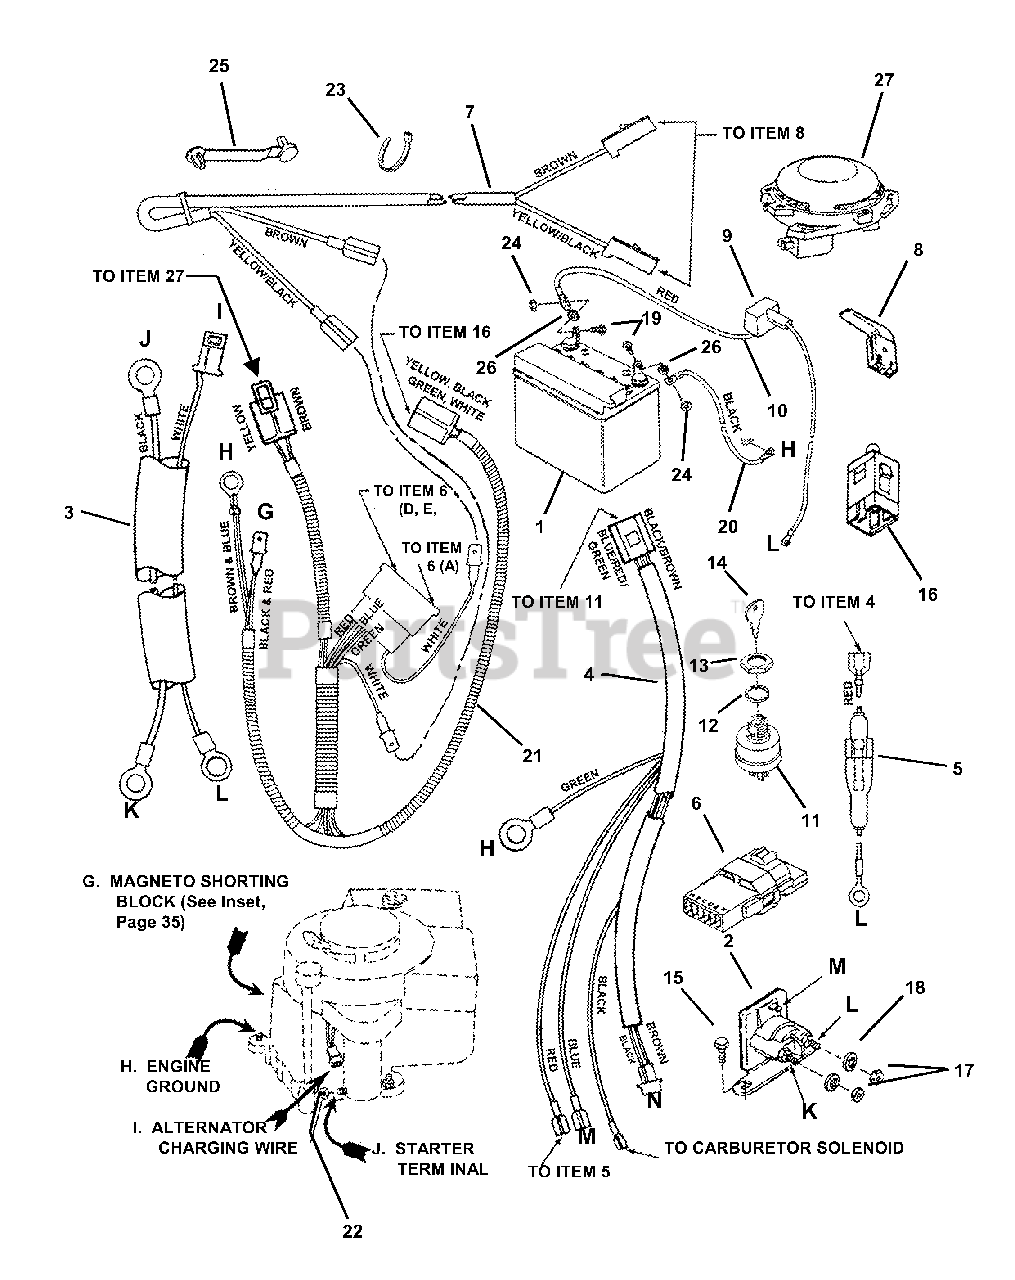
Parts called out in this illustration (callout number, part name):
1	KIT, 12V Dry Charge Battery
2	SOLENOID
3	HARNESS, Starter Wiring (Briggs)
4	HARNESS, Ignition Wiring (Briggs)
5	HOLDER, Fuse
6	INTERLOCK Module (Briggs)
7	HARNESS, (Deck Interlock Wiring)
8	SWITCH, Deck Interlock (NO)
9	COVER, Battery Cable
10	CABLE, Positive, 17" long (Red)
11	SWITCH, Ignition-Afterfire Solenoid
12	WASHER, 5/8" Internal Tooth Lock
13	NUT, 5/8-32 Hex
14	KEY, Switch
15	SCREW, 1/4-20 x 1/2" Hex Washer Self-Tap
16	SWITCH, Operator Presence Control (OPC) Traction (NC/NO)
17	NUT, 1/4-20 Hex, Grade 5 or B
18	WASHER, 1/4" Internal Tooth Lock
19	SCREW, 1/4-20 x 5/8" Hex Head Cap, Grade 5
20	CABLE, Negative (15")
21	HARNESS, Operator Presence Control Wire
22	NUT, 1/4-20 Hex, Grade 5 or B
23	TIE, 7" Long Cable
24	NUT, 1/4-20 Hex Cent er Lock, Grade 5 or B
25	TIE, 2" Long Cable
26	RETAINER, 1/4" Bolt
27	SWITCH, Seat (NC)
